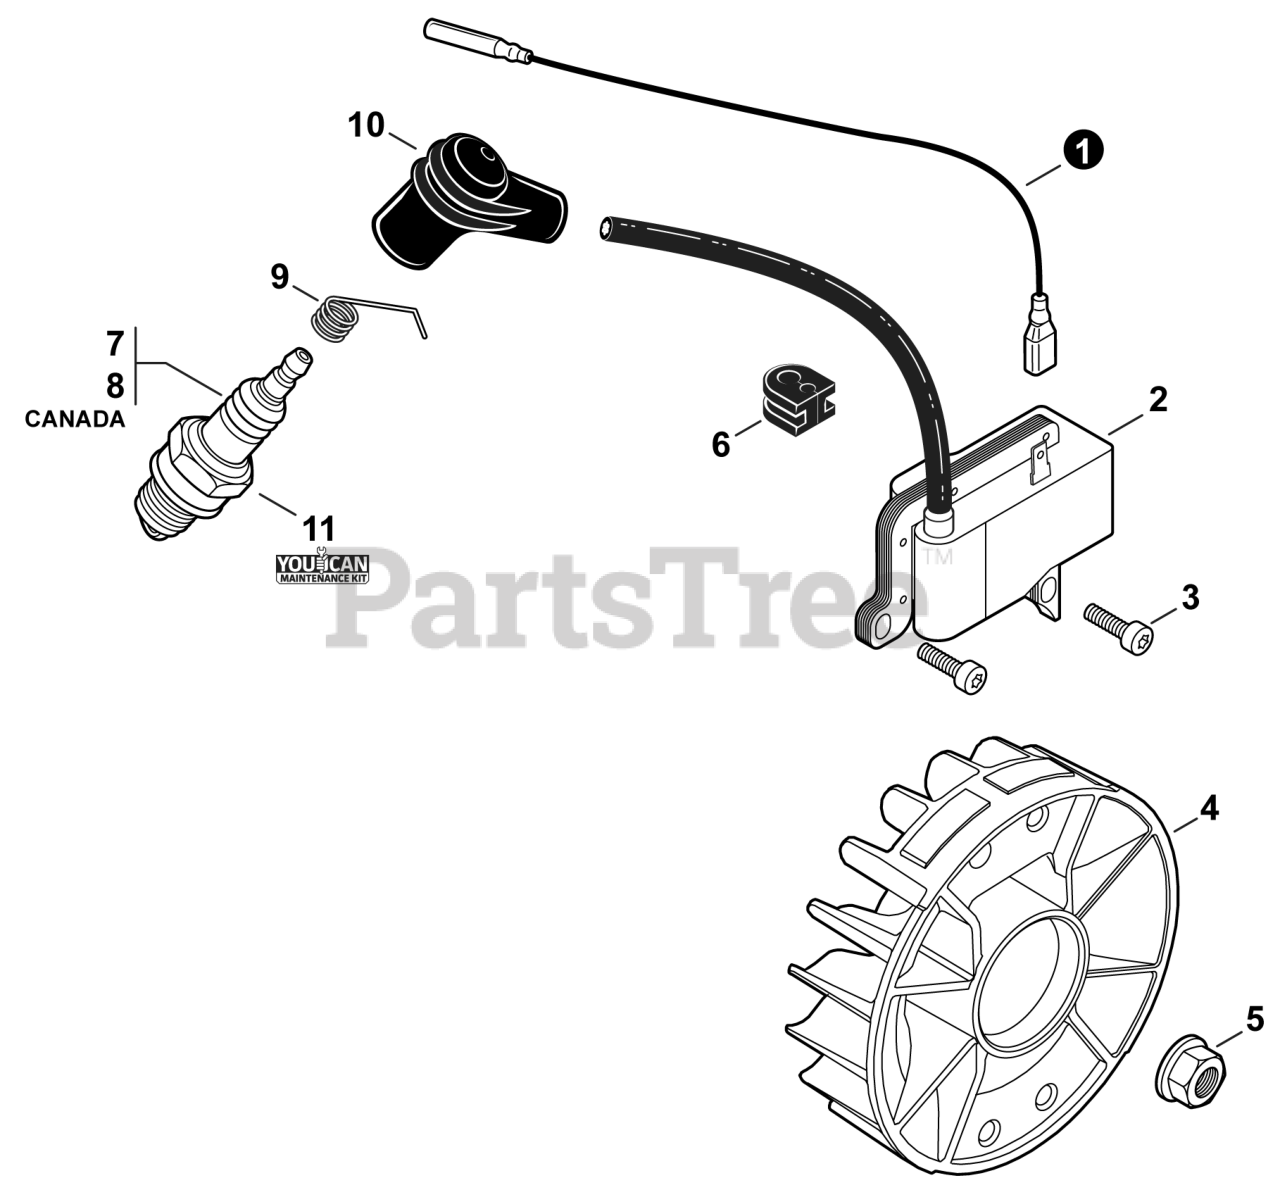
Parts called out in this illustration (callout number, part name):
1	LEAD L= 470
2	COIL, IGNITION
3	BOLT, TORX 5x20
4	FLYWHEEL
5	NUT, FLANGE 10x1.25
7	SPARK PLUG - BPM8Y
8	SPARK PLUG - BPMR8Y
9	TERMINAL, SPARK PLUG
10	CAP, SPARK PLUG
11	TUNE-UP KIT - YOUCANT
